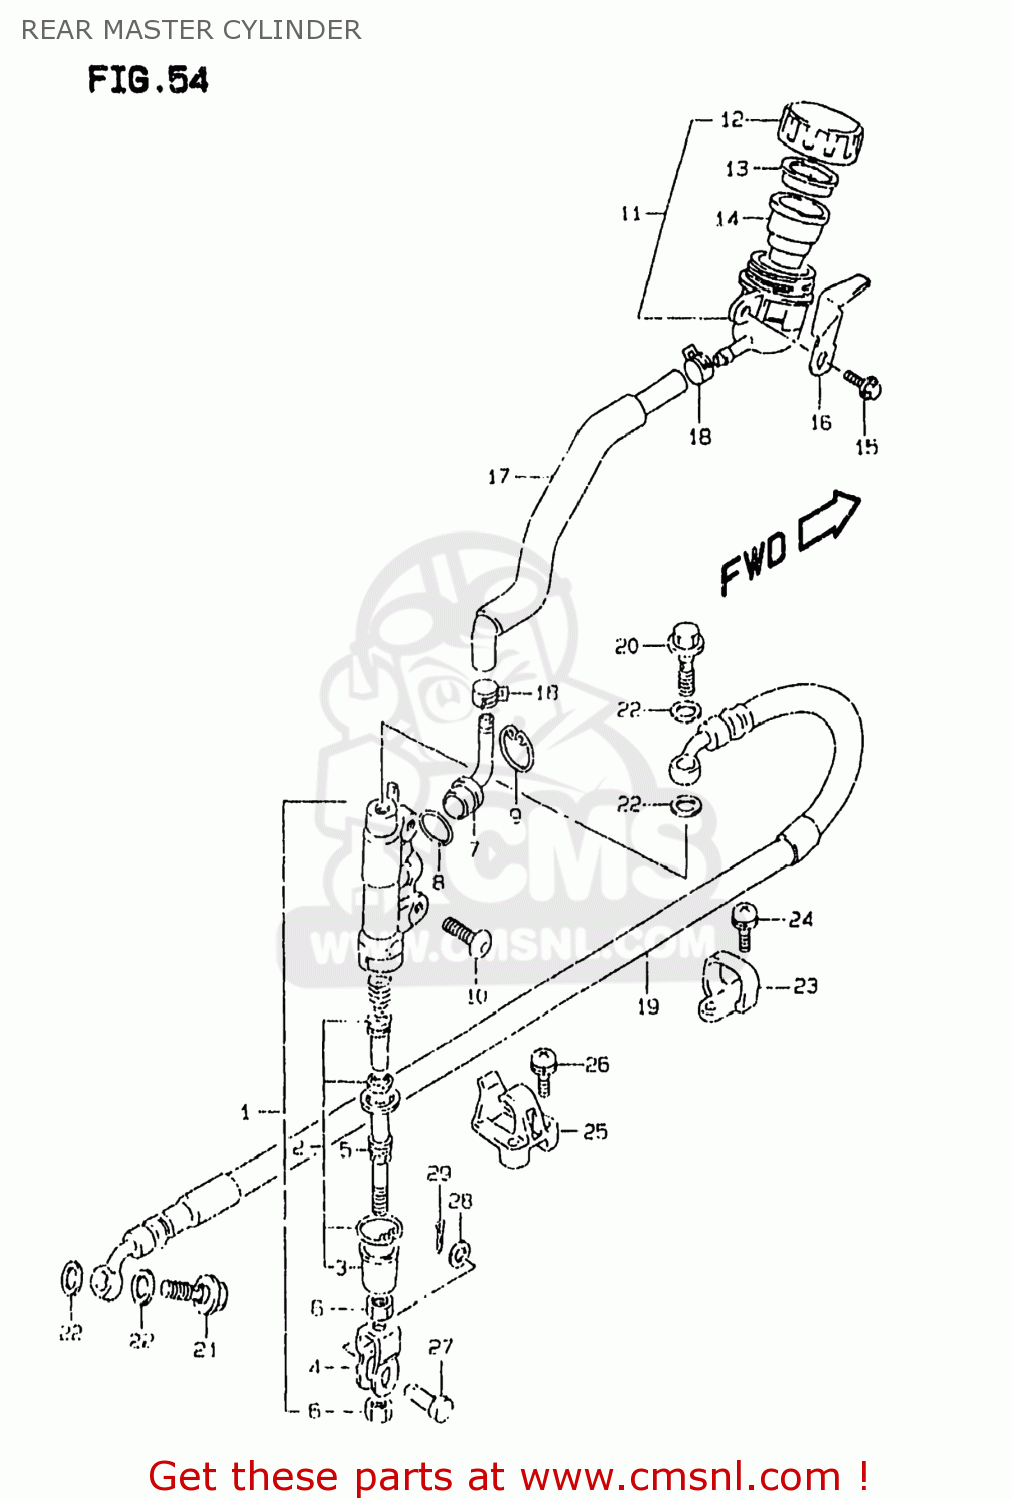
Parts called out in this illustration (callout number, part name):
1	CYLINDER ASSY,RR MASTER
2	PISTON/CUP SET
3	BOOT
4	YOKE
5	ROD,PUSH
6	NUT
7	CONNECTOR
8	O RING
9	CIRCLIP
10	SCREW(6X16)
11	TANK ASSY,RR BRAKE RESERVOIR
12	CAP
13	PLATE
14	DIAPHRAGM
15	BOLT
16	GUARD,RSVR TANK CAP
17	HOSE COMP,RESERVOIR TANK
18	CLIP
19	HOSE,RR BRAKE
20	BOLT UNION
21	BOLT UNION
22	WASHER(10X15X1.5)
23	GUIDE,RR BRAKE HOSE
24	SCREW
25	GUIDE,RR BRAKE HOSE
26	SCREW
27	PIN(8X20)
28	WASHER(8.5X13X1.6)
29	PIN 20X15
